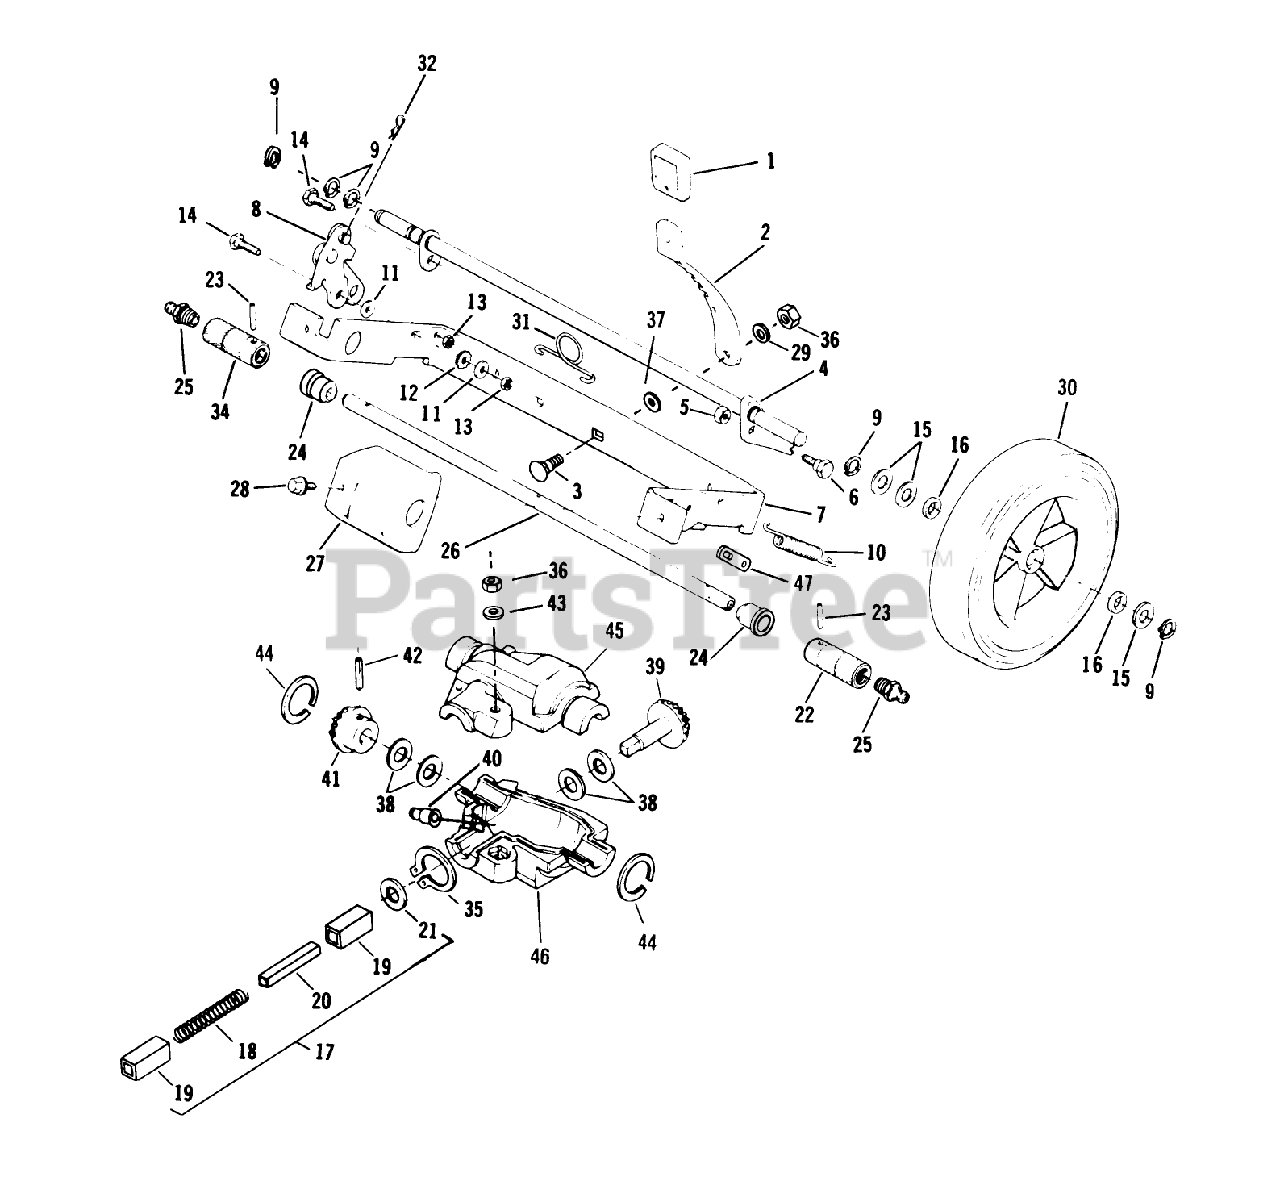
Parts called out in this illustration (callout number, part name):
2	LEVER
5	LOCKNUT E
6	BOLT RB&W
7	BRACKET *GREEN
8	CLUTCH AY ARGO
9	RET RING
10	SPRING
11	WASHER S
13	STOP NUT
14	BOLT RB&W
15	SPACER
16	WASHER
18	SPRING
19	BUSHING BKWY
21	THRUST WASHER
22	ROLLER (LEFT) VS
22	ROLLER-LH
23	PIN
24	SLEEVE &BEARING AY
25	GREASE FITTING AP
26	DRIVE SHFT TAG AY
29	WASHER S
30	WHEEL & TIRE KIT
31	SPRING N.A.S
34	ROLLER (RIGHT) VS
34	ROLLER-RH
36	LOCKNUT E
37	WASHER SPRING LAR
38	THRUST WASHER
39	GEAR BEST
40	ZERK FITTING
41	GEAR ADVANCE
42	ROLL PIN
43	WASHER F
